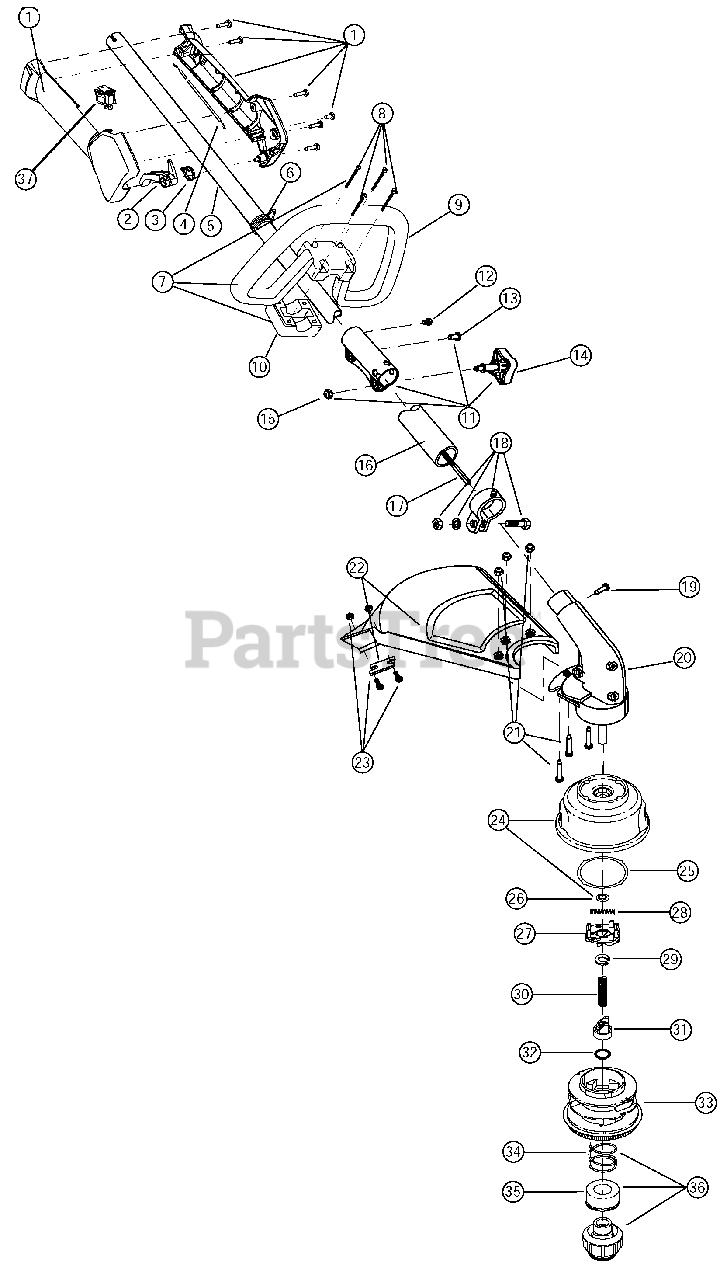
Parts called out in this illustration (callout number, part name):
1	Throttle Housing and Trigger Assembly
2	Throttle Trigger
3	Throttle Trigger Spring
4	Throttle Cable Assembly
5	Upper Drive Shaft Housing Assembly
6	Harness Clip
7	Deluxe D-Handle Assembly
9	Deluxe D-Handle
10	Bottom Clamp
11	EZ-Link(TM) Coupler
14	Adjustment Knob
16	Lower Drive Shaft Housing Assembly
17	Lower Flexible Drive Shaft
18	Lower Clamp Assembly
19	Anti-Rotation Screw
20	Gear Box Assembly
21	Shield Mounting Hardware
22	Shield and Blade Assembly
23	Blade Assembly
24	Outer Spool and Eyelet Assembly w/ Retainer
25	Retainer
26	Thrust Washer
27	Slider
28	Small Spring
31	Plunger
33	Inner Reel
34	Large Spring
35	Foam Seal
36	Bump Head Knob Assembly
37	Switch Assembly
